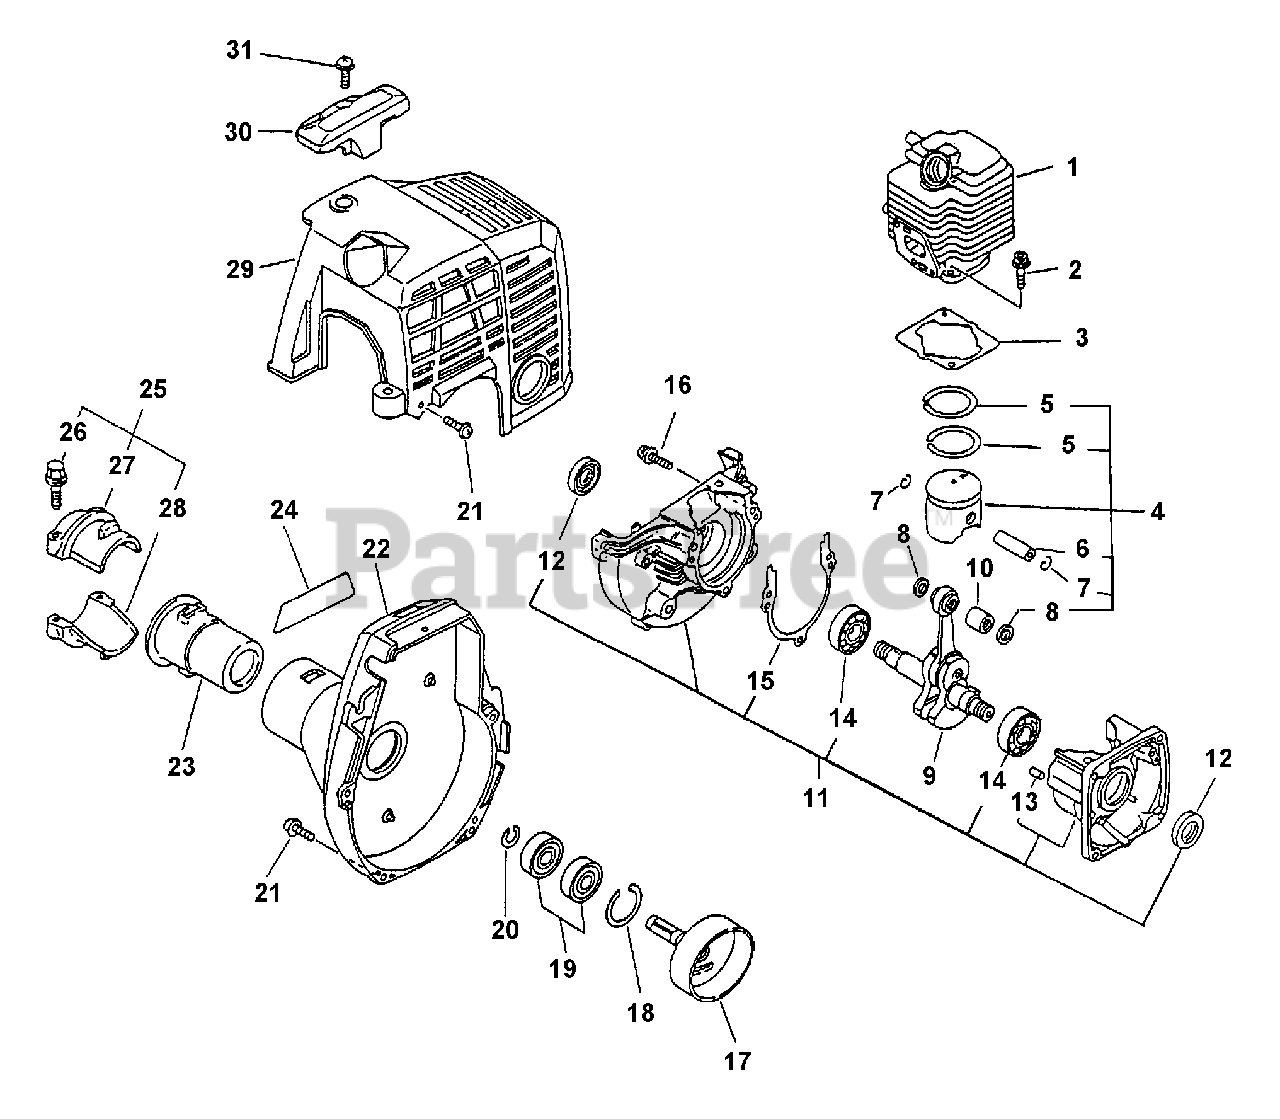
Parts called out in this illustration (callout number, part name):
1	CYLINDER
2	BOLT 5×22
3	GASKET, CYLINDER
4	PISTON KIT
5	RING, PISTON
6	PIN, PISTON 8
7	RING, SNAP
8	WASHER, THRUST
9	CRANKSHAFT ASSY
10	BEARING, NEEDLE
11	CRANKCASE KIT
12	SEAL, OIL 12
13	PIN, LOCATING 4
14	BEARING, BALL - 6201 C3
15	GASKET, CRANKCASE
16	BOLT 5×28
17	DRUM, CLUTCH
18	RING, SNAP 28
19	BEARING, BALL 6001
20	RING, RETAINING - 12
21	BOLT 4×16
22	COVER ASSY, FAN
23	CUSHION Ø25
24	LABEL, MODEL
25	RETAINER KIT
26	BOLT - 5×25
27	HOLDER, MAIN PIPE - UPPER
28	HOLDER - LOWER
29	COVER, ENGINE
30	GUARD, TOP
31	SCREW 5×16
